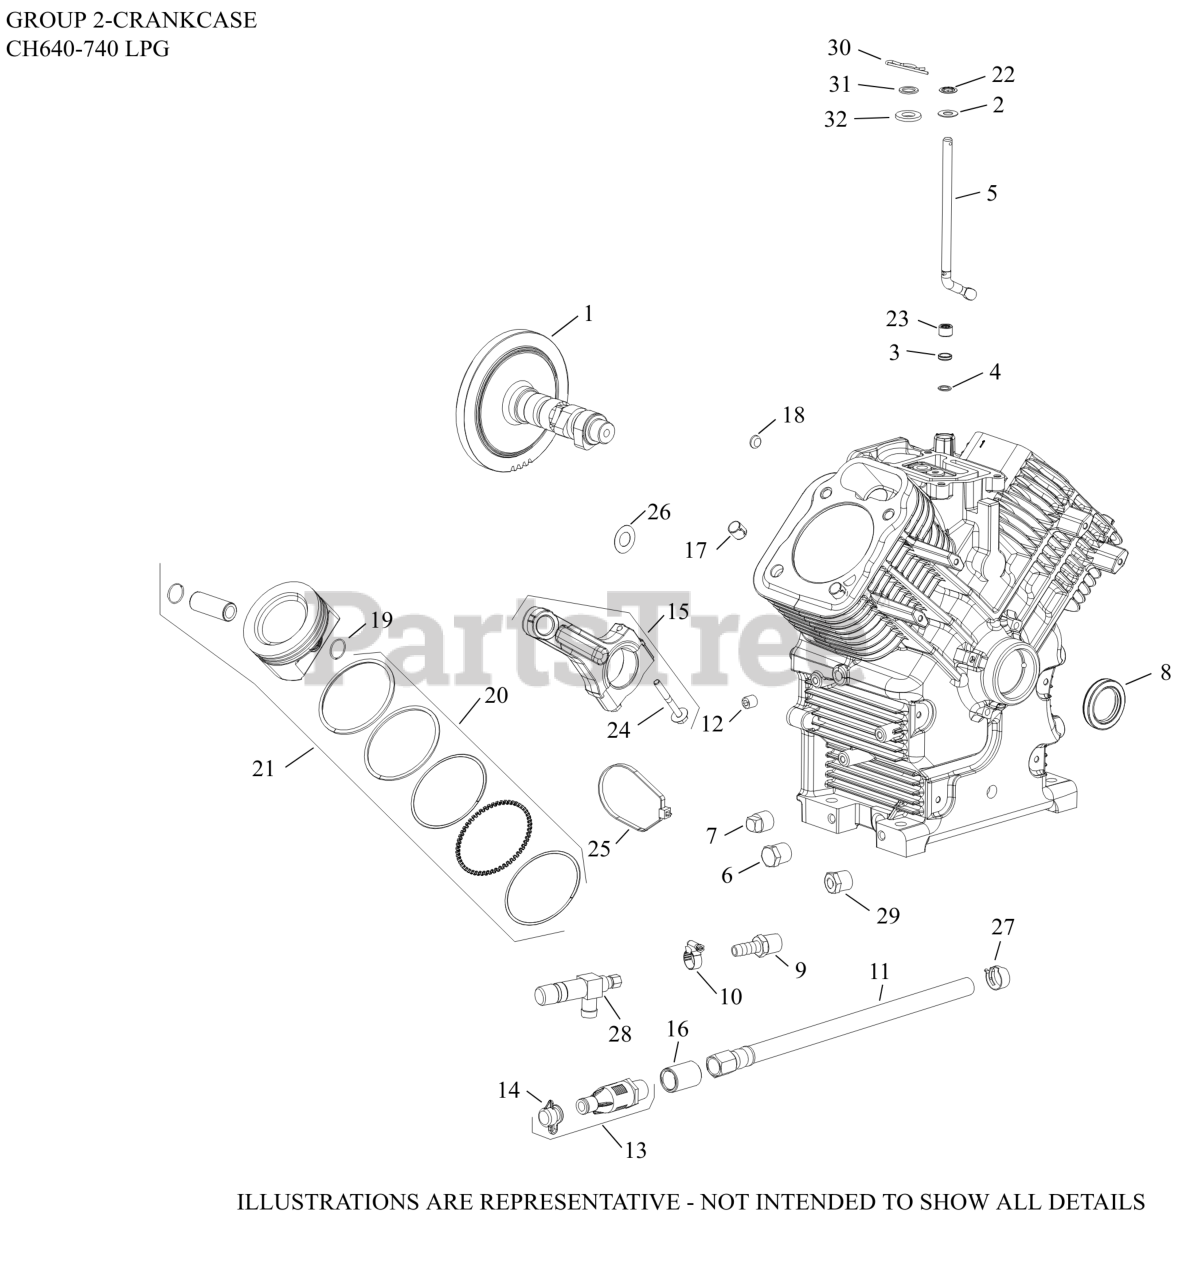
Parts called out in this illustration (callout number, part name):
1	KIT, CAMSHAFT-(#2401226S)
2	WASHER, FLAT 9 MM
3	SEAL, GOVERNOR CROSS SHAFT
4	WASHER, FLAT 11/32"
5	SHAFT, GOVERNOR CROSS
8	SEAL, OIL (HELIX LIP)
12	PLUG, CTSK PIPE 1/8"
17	PIN, LOCATING
18	PLUG, CUP
19	RETAINER, PISTON PIN
20	RING SET(STD)STYLE B-1.2mm Tp RING THICK
20	RING SET(.08)STYLE B-1.2mm RING THICK
20	RING SET(.25)STYLE B-1.2mm Tp RING THICK
20	RING SET(.50)STYLE B-1.2mm Tp RING THICK
21	KIT, PISTON 725CC (STD) STYLE B
21	KIT, PISTON 725CC (.08) STYLE B
21	KIT, PISTON 725CC (.25) STYLE B
21	KIT, PISTON 725CC (.50) STYLE B
22	RETAINER, RING
23	BEARING, NEEDLE
24	KIT, ROD BOLTS-(#25086677S)
49	PLUG, SQ HD PIPE 3/8"
NI	ROD, ASSEMBLY CONNECTING
